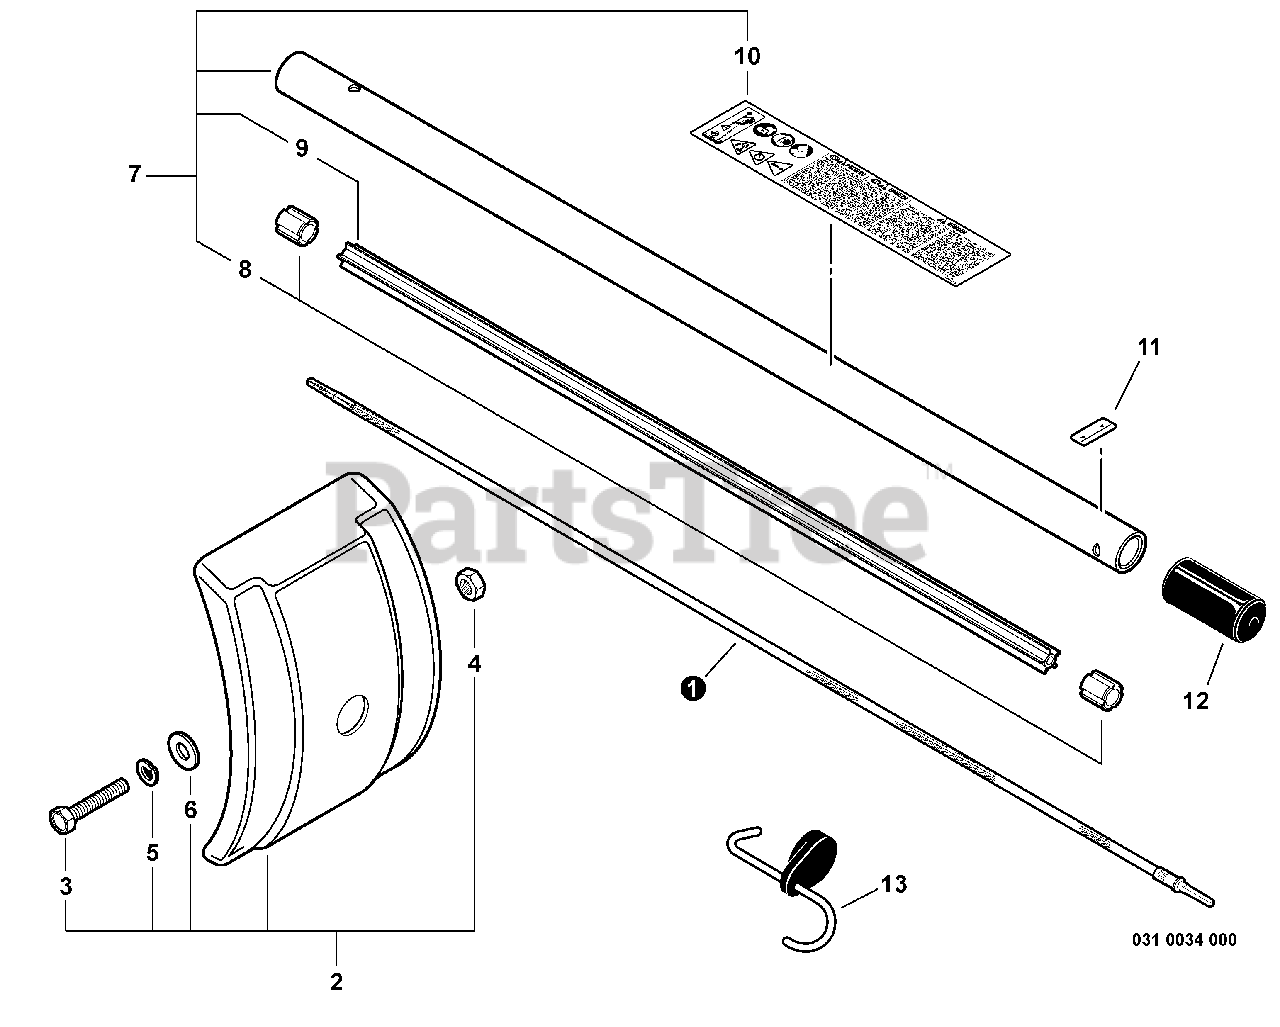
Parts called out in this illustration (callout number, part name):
1	DRIVESHAFT - FLEXIBLE
2	DEBRIS SHIELD KIT
3	BOLT - 6X20
4	LOCKNUT - 6
5	LOCKWASHER - 6
6	WASHER - 6
7	MAIN PIPE ASSY
9	LINER - FLEXIBLE
10	LABEL - CAUTION
11	LABEL - ALIGNMENT
13	PAS ATTACHMENT HANGER
